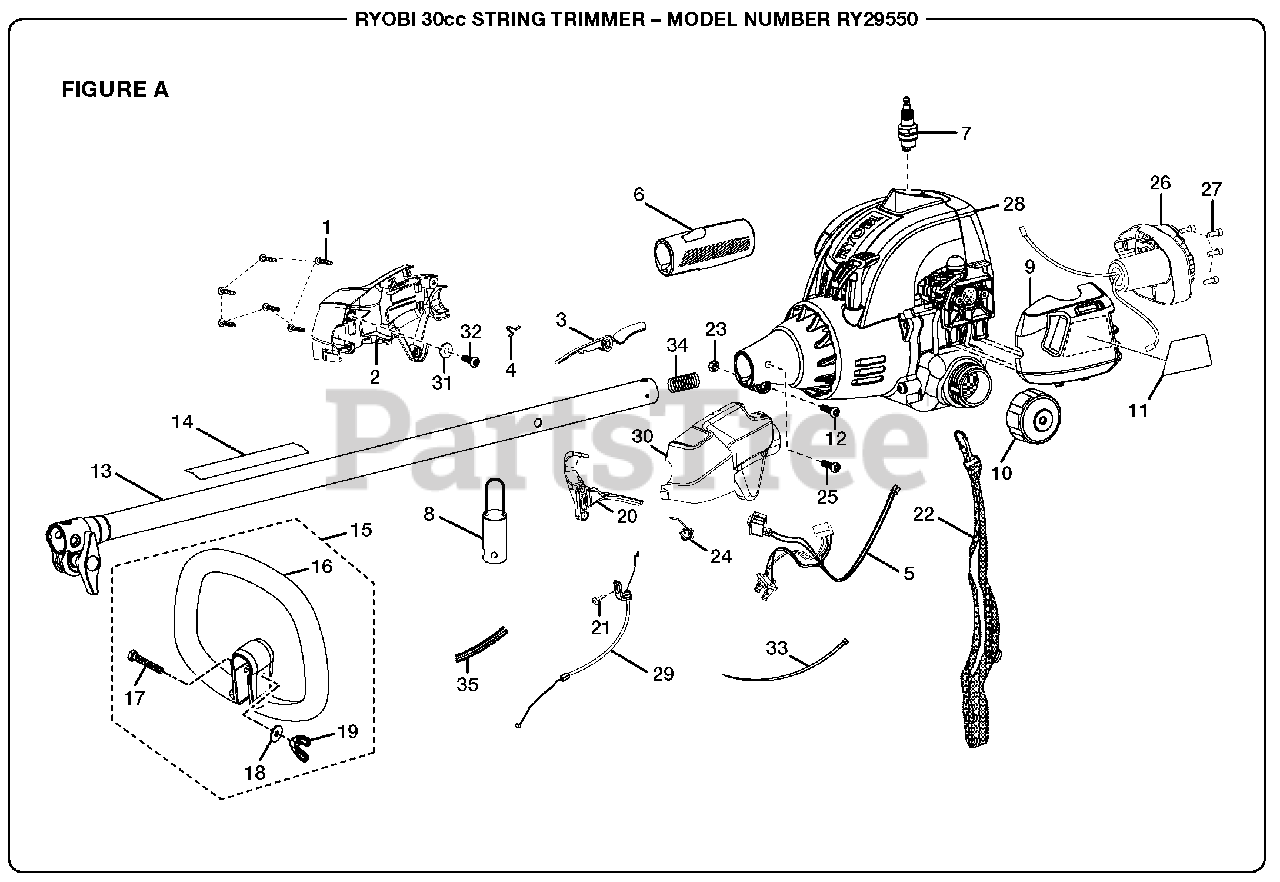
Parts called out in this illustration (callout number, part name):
1	Screw (M4 x 18 mm)
2	Left Handle
3	Trigger Lock
4	Strap Hanger
5	Wire Harness
6	Rear Handle
7	Spark Plug (Champion RCJ6Y)
8	Hanger Cap
9	Air Box Cover
10	Fuel Cap Assembly
12	Bolt (M6 x 20 mm)
13	Upper Boom Assembly
14	Warning Decal
15	Front Handle Assembly
16	Front Handle
17	Bolt (1/4-20 x 40 mm)
19	Wing Nut (1/4-20)
20	Throttle Trigger
21	Screw (10-24 x 7/8 in.)
22	Shoulder Strap
23	Hex Nut (M6)
25	Bolt (8-16 x 5/16 in. Torx T.F.)
26	Electrical Start Assembly
27	Screw (M5 x 14 mm)
28	Power Head Assembly
29	Throttle Cable
30	Right Handle
32	Screw
33	Cable Tie
34	Spring
